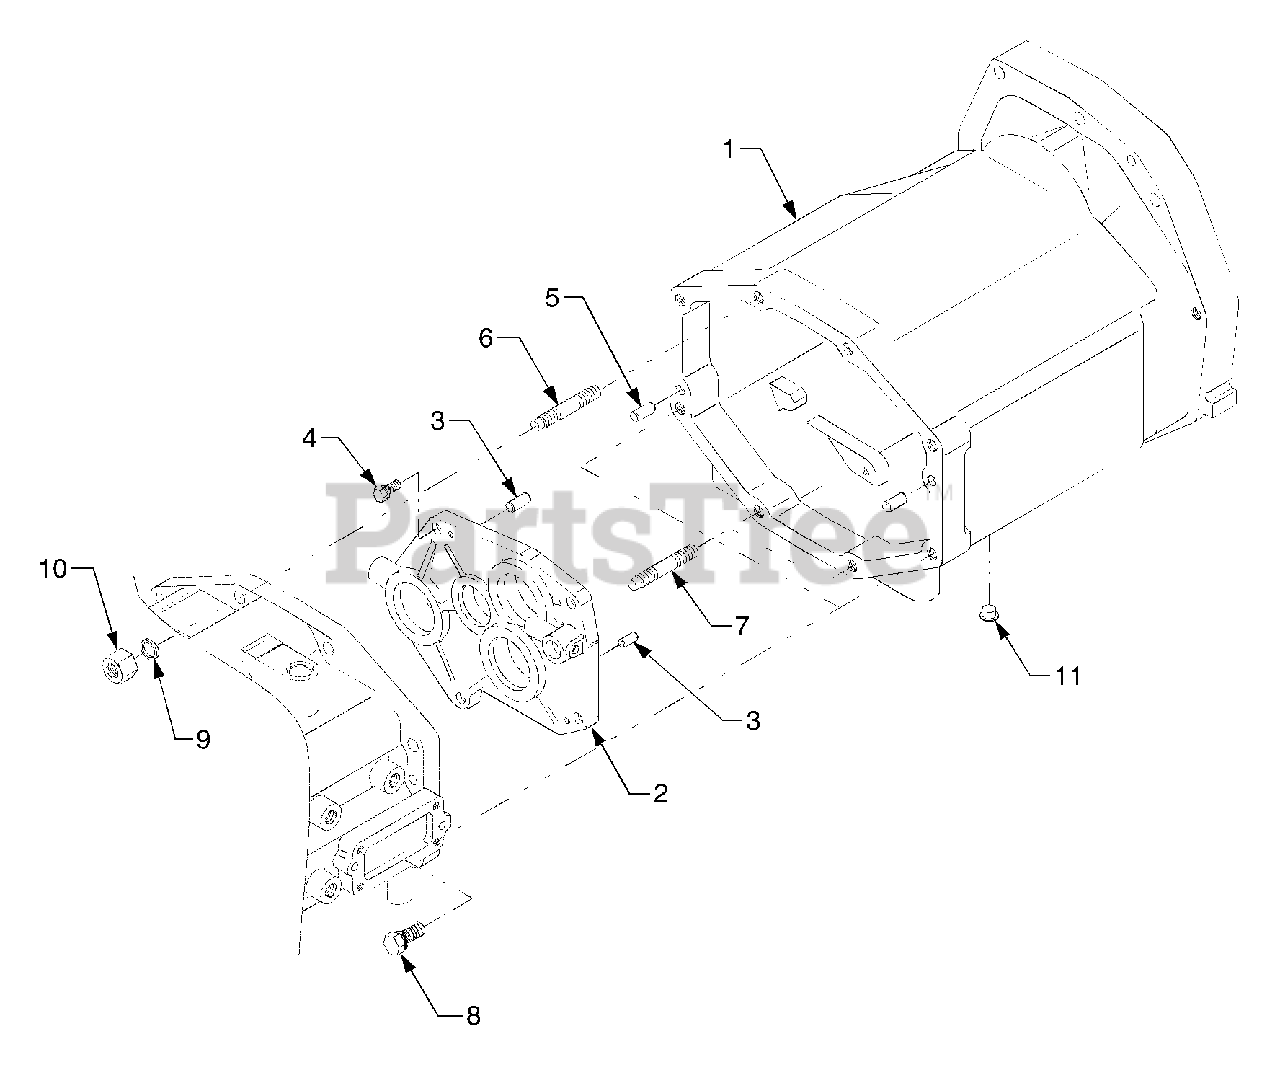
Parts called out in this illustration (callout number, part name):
2	Cover, Bearing
3	Pin, Straight
5	Pin, Straight
9	Washer, Spring
